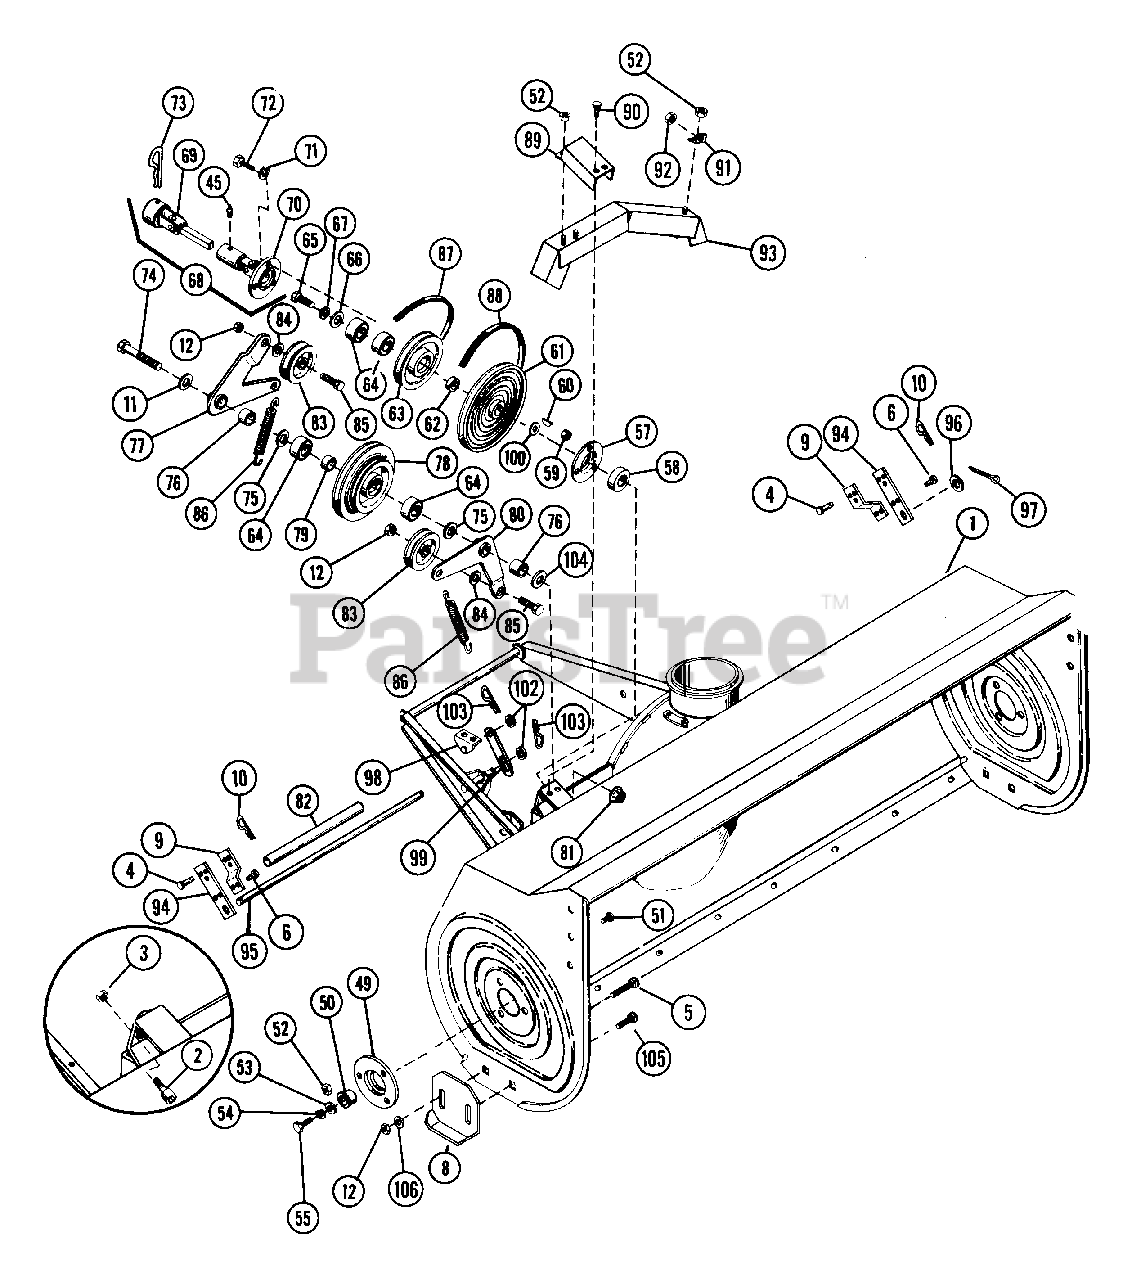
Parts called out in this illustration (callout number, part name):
1	BLOWER HOUSING ASSEMBLY
2	SCR-SKH 10-24X.38
3	NUT-LK DUAL FACE 10-24 PL
4	CLEVIS PIN
5	BLT-RDHDSQSHNK .38-16X1.00 PL
6	SCR-TAP .312-18X.50 HWH PL TR
8	RUNNER-SKID SHOE
9	SUPPORT
10	PIN-HAIR INT .08X.18X1.18
11	WSHR-FL-STL .765X1.250X.093
12	NUT-LK-CTR .375-16 GR A PL
45	SPIN DRIVE ZERK FITTING
49	BEARING SUPPORT
50	BSHG-FLG 1.000X1.12X.62X1.50BR
51	BLT-SERNK SL .25-20X.50 PL
52	NUT-LK-FLG .250-20 PL
53	WSHR-FL-STL .511X1.441X.125 PL
54	WSHR-LK .500X.151 HVY PL
55	BLT-HEX .50-13X1.00 PL GR2
57	BEARING FLANGE
58	BRG-BALL 1.0X2.0X.56
59	NUT-LK-CTR .250-20 PL
60	KEY-WDRF .188X.875X.375 SAE11
61	PLY-V 10.00 X .88 W/KEY SALEM
62	SPACER .906X1.125X.453
64	BRG-BALL .750X1.781X.61
65	BLT-HEX .38-16X1.00 PL
66	WSHR-FL-STL .438X1.0X.083 PL
67	WSHR-LK .375X.094 MED PL
68	UNIVERSAL SHAFT ASSEMBLY
69	UNIVERSAL SPLINE HALF
70	UNIVERSAL PLATE HALF
71	WSHR-LK .250X.077 HVY PL
72	BLT-HEX .25-20X.75 PL GR2
73	PIN-HAIR INT .18X1.18X3.25 PL
74	BLT-HEX .75-10X5.50 GR2
75	WSHR-FL-STL .781X1.500X.188
76	BSHG-SLV .750X1.125X1.062
77	IDLER ARM
79	SPACER .781X1.000X.547
80	IDLER ARM
81	NUT-LK-FLG .75-10 GR F PL
82	TUBE .725 X .875 X 14.00
83	IDLER-FLAT 3.00 X .38 CLK.&CAP
84	WSHR-FL-STL .406X.875X.135
85	BLT-HEX .38-16X1.25 PL GR 2
86	SG-TENS 6.0 FREE LENGTH
87	V-BELT, HA-RAW EDGE
88	V-BELT, 4L-RAW EDGE
89	COVER
90	SCR-TAP .250-20X.37 HWH PL TR
92	NUT-FLG. .312-18 PL
93	BELT GUARD
94	LIFT LINK
96	WSHR-FL-STL .688X1.75X.134PL
97	PIN-COTR .12 X 1.25 PL
98	LIMITING POST
99	LIMITING ARM
100	WSHR-FL-STL .880X1.250X.062
102	WSHR-FL-STL .531X1.062X.095 PL
103	PIN-HAIR INT .09X.188 PL
104	WSHR-HDND-THRST .755X1.40X.062
105	BLT-RDHDSQNK .38-16X.75 SHT PL
106	WSHR-FL-STL .38X.875X.083 PL
